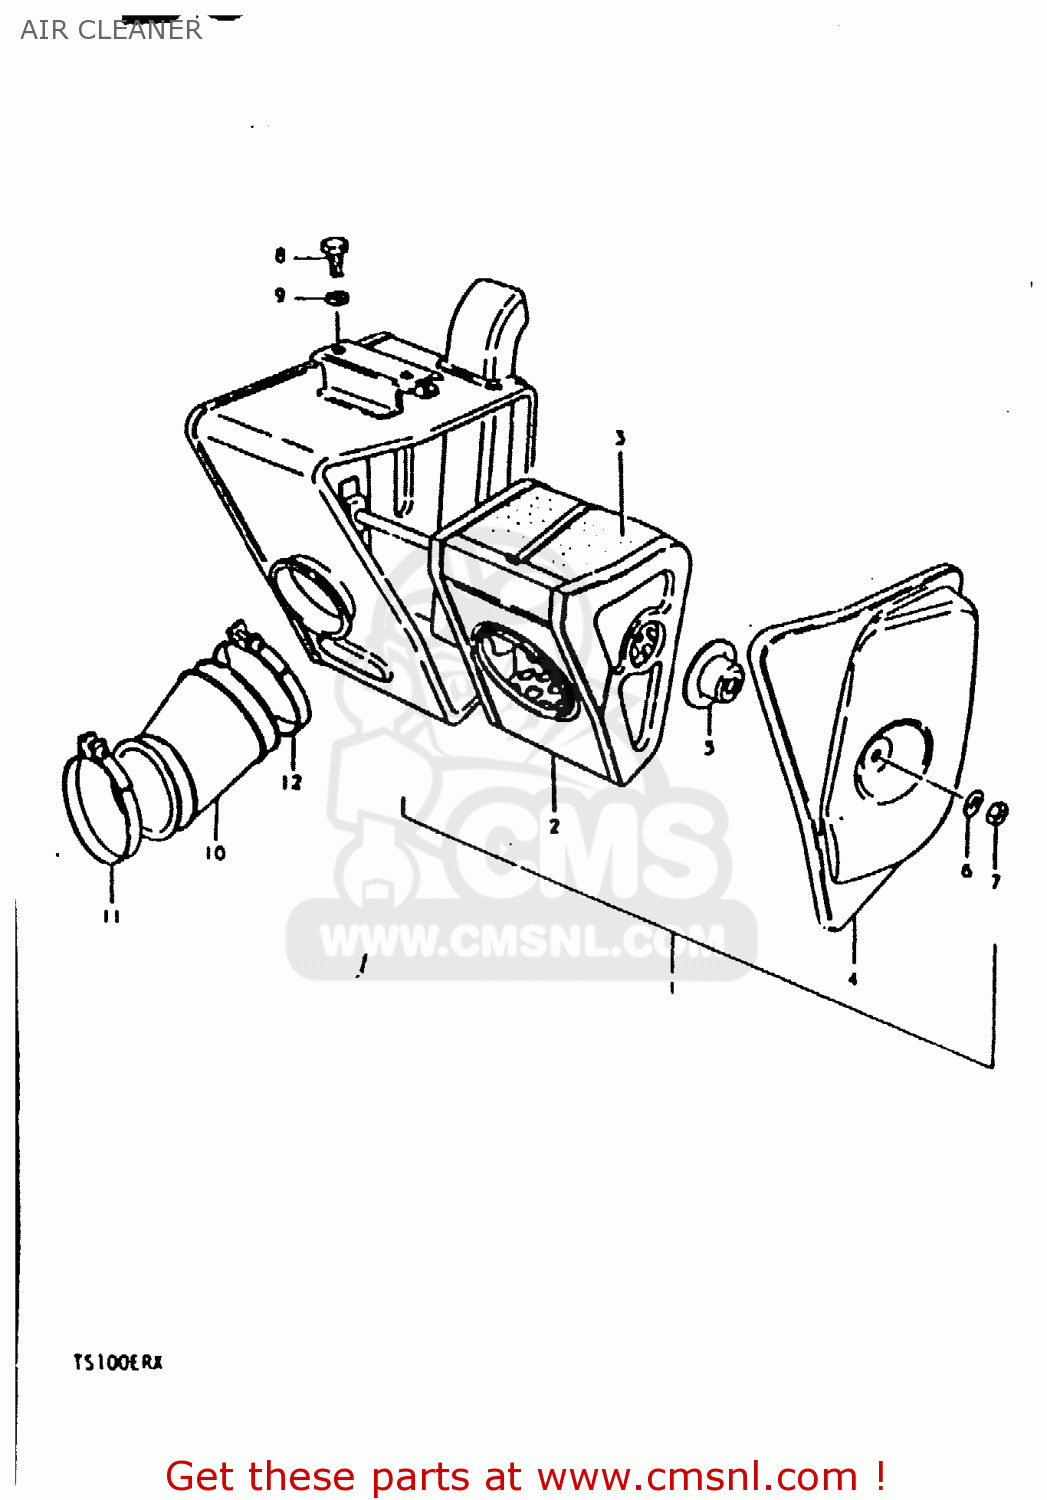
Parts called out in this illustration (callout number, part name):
1	CLEANER ASSEMBLY,AIR
2	FILTER ASSY,AIR CLEANER
3	FILTER
4	CAP
5	SPACER
6	WASHER
7	NUT
8	BOLT
9	WASHER
10	HOSE,CARBURETOR AIR INLET
11	CLAMP
12	CLAMP
